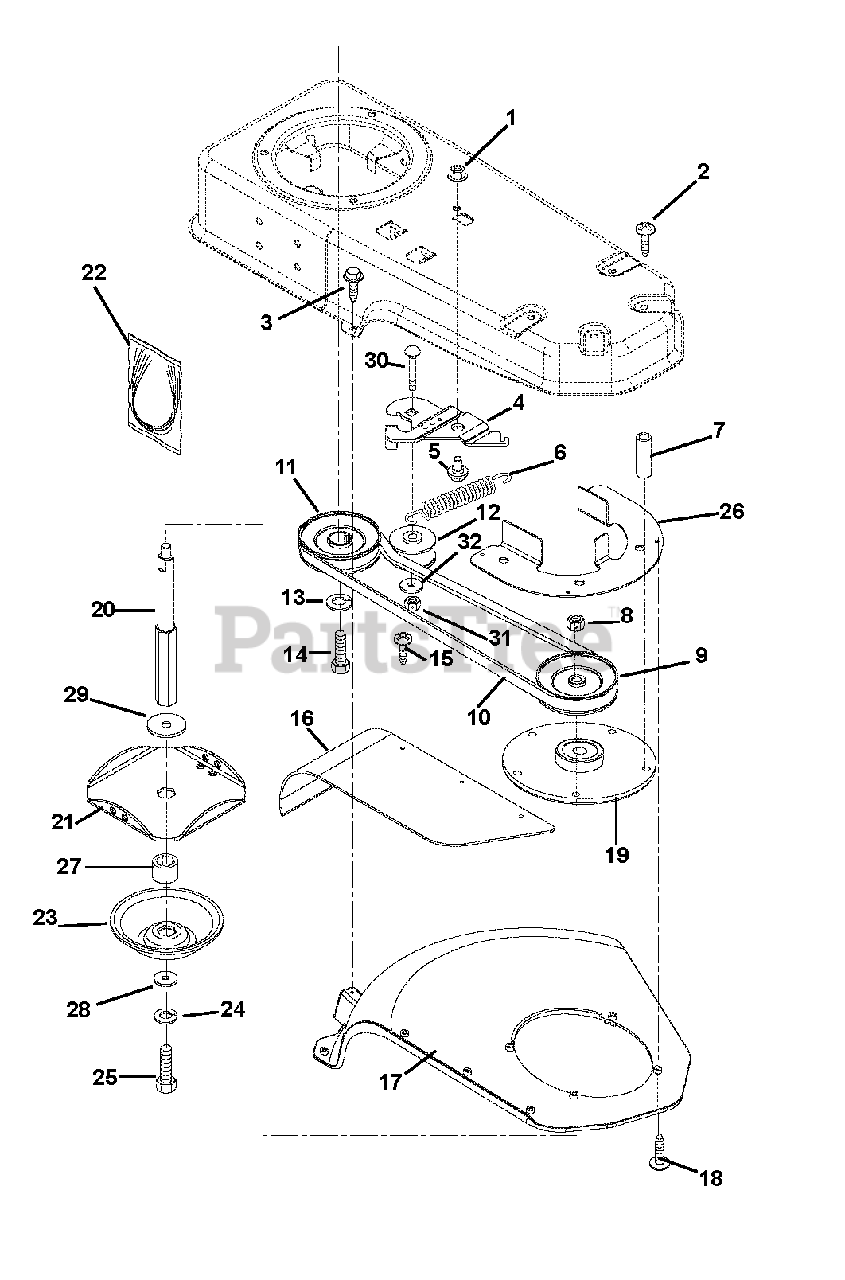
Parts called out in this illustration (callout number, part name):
1	NUT-LK-CTR-FLG .38-16 YWZC
2	@SCR-TAP.375-16X2.75 HWH TR YZ
3	SCR-TAP 10-24X.75 HWH TR YWZC
4	BRACKET - IDLER
5	BOLT-SHLDR .375-16X.150
6	SG-TENS .035X.45X2.75 WLD 3.5
7	BSHG-SPCR .406X.625X1.90
8	NUT-LK-FLG .375-24 GR5 YWZC
9	PLY-V 3.50 OD X .87 WIDE (CUT)
10	V-BELT, HA-RAW EDGE
11	SHEAVE-ENGINE 3.50 ODX.87 WIDE
12	IDLER - FLAT 1.875OD X .75WIDE
13	@WSHR-LK .38X.094 REG YWZC
14	BLT-HEX .38-24X1.0 YWZC GR5
15	SCR-TAP #10-16 X .625 HWH
16	GUARD - DEBRIS
17	SHIELD - TRIMMER
18	SCR-TAP 10-24X.75 HWH TR YWZC
19	HOUSING, JACKSHAFT -CHAMFERED
20	SHAFT - CUTTER - HEX
21	DISC - CUTTER - HEX
22	LINE - CUTTER 18" LG PKG OF 6
23	GUIDE - HEIGHT - HEX
24	@WSHR-LK .31X.078 REG YWZC
25	@BLT-HEX .31-18X.75 GR5 YWZC
26	FINGER - BELT
27	SPACER - HEX
28	WSHR-FL-STL .344X1.125X.135
29	SHIELD - DUST
30	@BLT-RHDSSQNK .38-16X1.50 G5YZ
31	@NUT-LK-CTR .38-16 YWZC
32	@WSHR-FL-STL.406X.812X.065 YWZ
